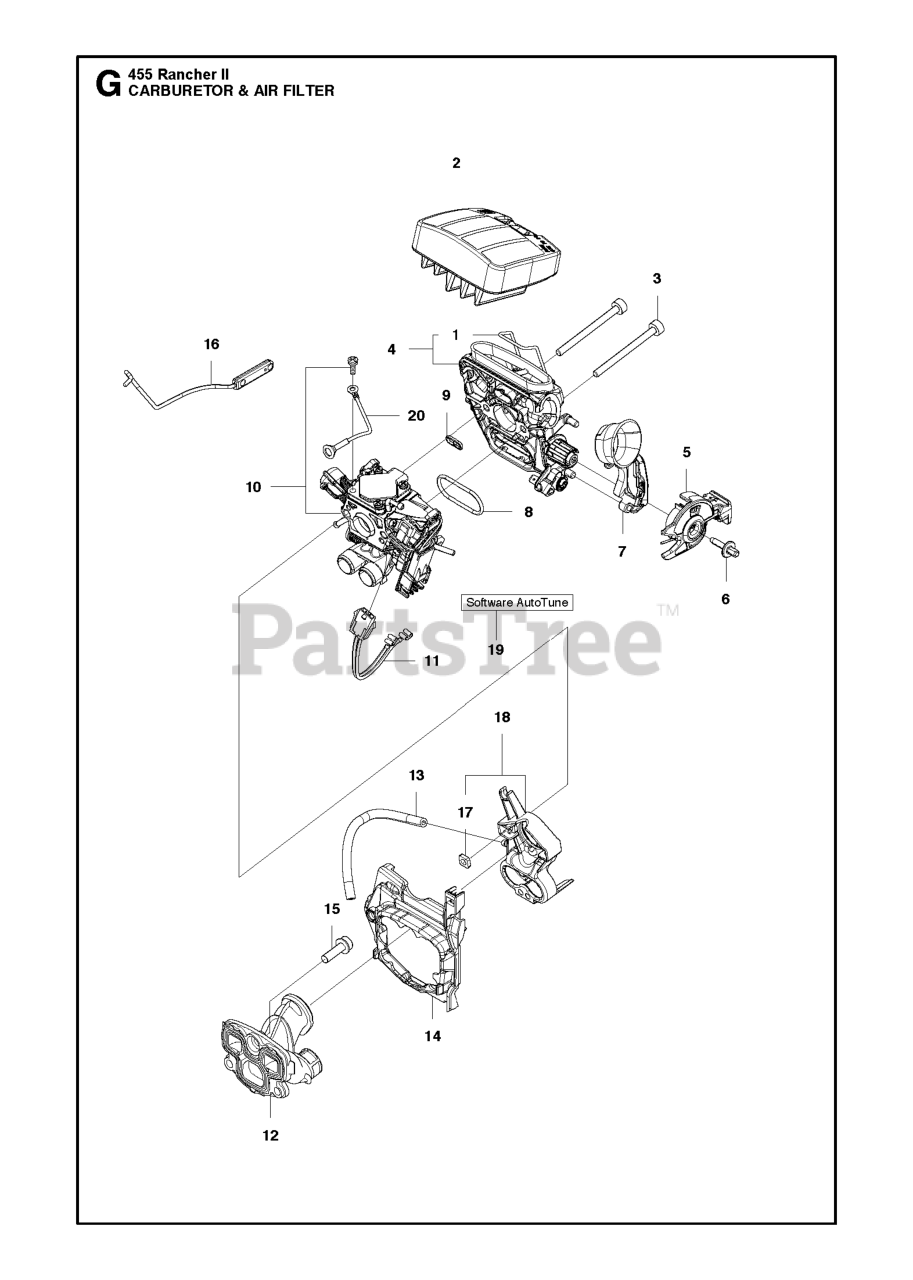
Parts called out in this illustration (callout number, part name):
2	AIR FILTER ASSY
3	SCREW
4	FILTER HOLDER ASSY
5	CHOKE CONTROL ASSY CHOKE/STOP
10	CARBURETOR
11	WIRING ASSY
12	INLET PIPE ASSY
13	HOSE
15	SCREW
16	THROTTLE ROD
17	NUT
20	WIRING ASSY
